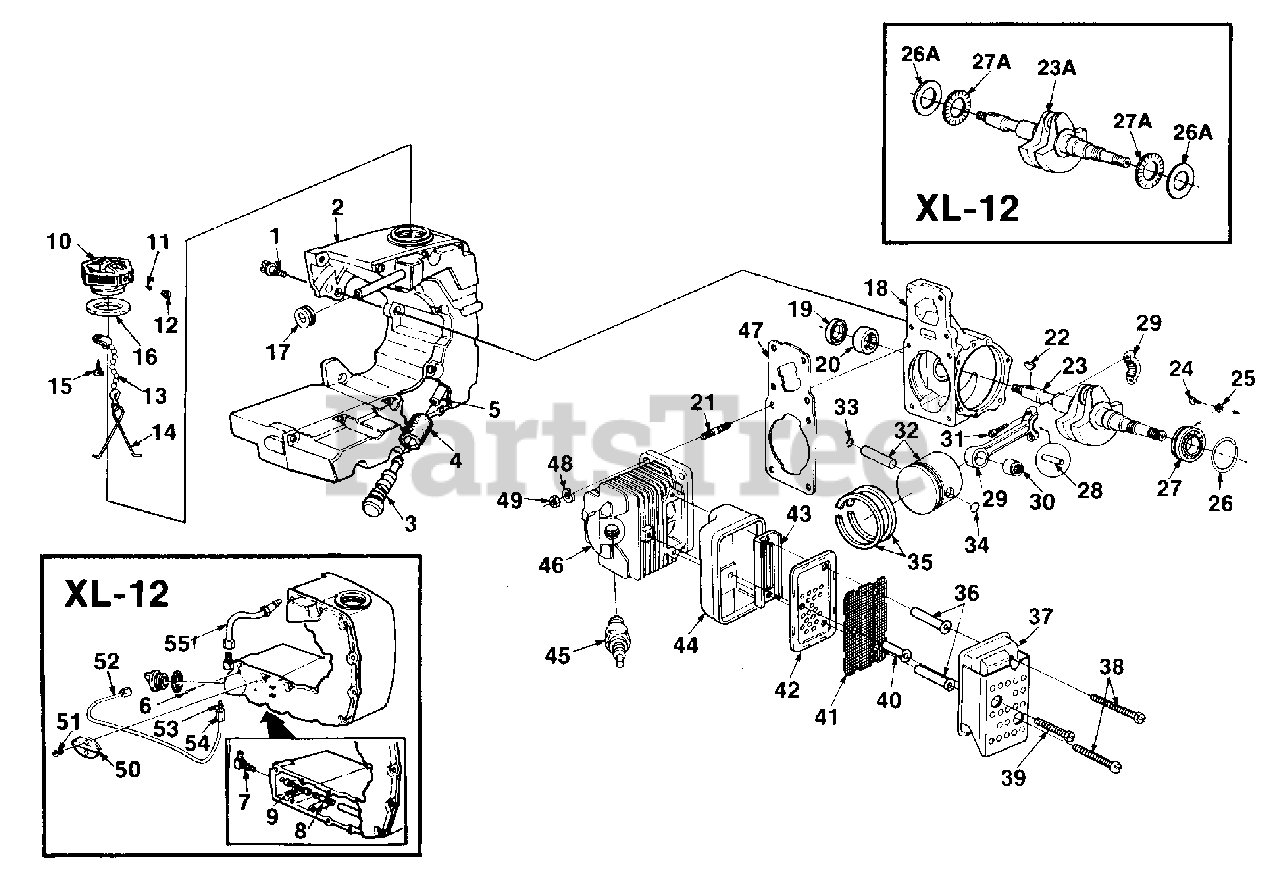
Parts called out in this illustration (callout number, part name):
1	SCREW- Shoulder
2	TANK- Fuel
3	FILTER- Fuel
4	FELT- Filter
5	TUBING- Fuel 9 1/4"
10	CAP- Fuel filler
11	VALVE- Check
12	FILTER- Fuel cap
13	CHAIN- Bead
14	RETAINER
15	SCREW- Pan hd. #6 x 1/4
16	GASKET- Fuel filler cap
17	GROMMET
18	CRANKCASE
19	SEAL
20	BEARING
21	STUD
22	KEY- Woodruff
23	CRANKSHAFT
24	SCREW- Torx
25	WASHER- Lock
26	RING- Retaining
27	BEARING- Ball
28	ROLLER SET (31)
29	ROD- Connecting
30	BEARING
31	SCREW- Cap soc. hd.
32	PISTON & PIN
33	RING- Retaining
34	RING- Retaining
35	PISTON RING
36	SPACER- Muffler
37	CAP- Muffler & Shield
38	SCREW- Hex hd. (12-24 x 2 1/4)
39	SCREW- Hex hd. (12-24 x 1 7/8)
40	SPACER- Muffler
41	SCREEN- Spark arrestor
42	BAFFLE- Muffler
43	PLATE- Muffler
44	BODY- Muffler
45	SPARK PLUG (CJ6)
46	CYLINDER
47	GASKET- Cylinder
48	WASHER- Lock 1/4
49	NUT- 1/4-28
